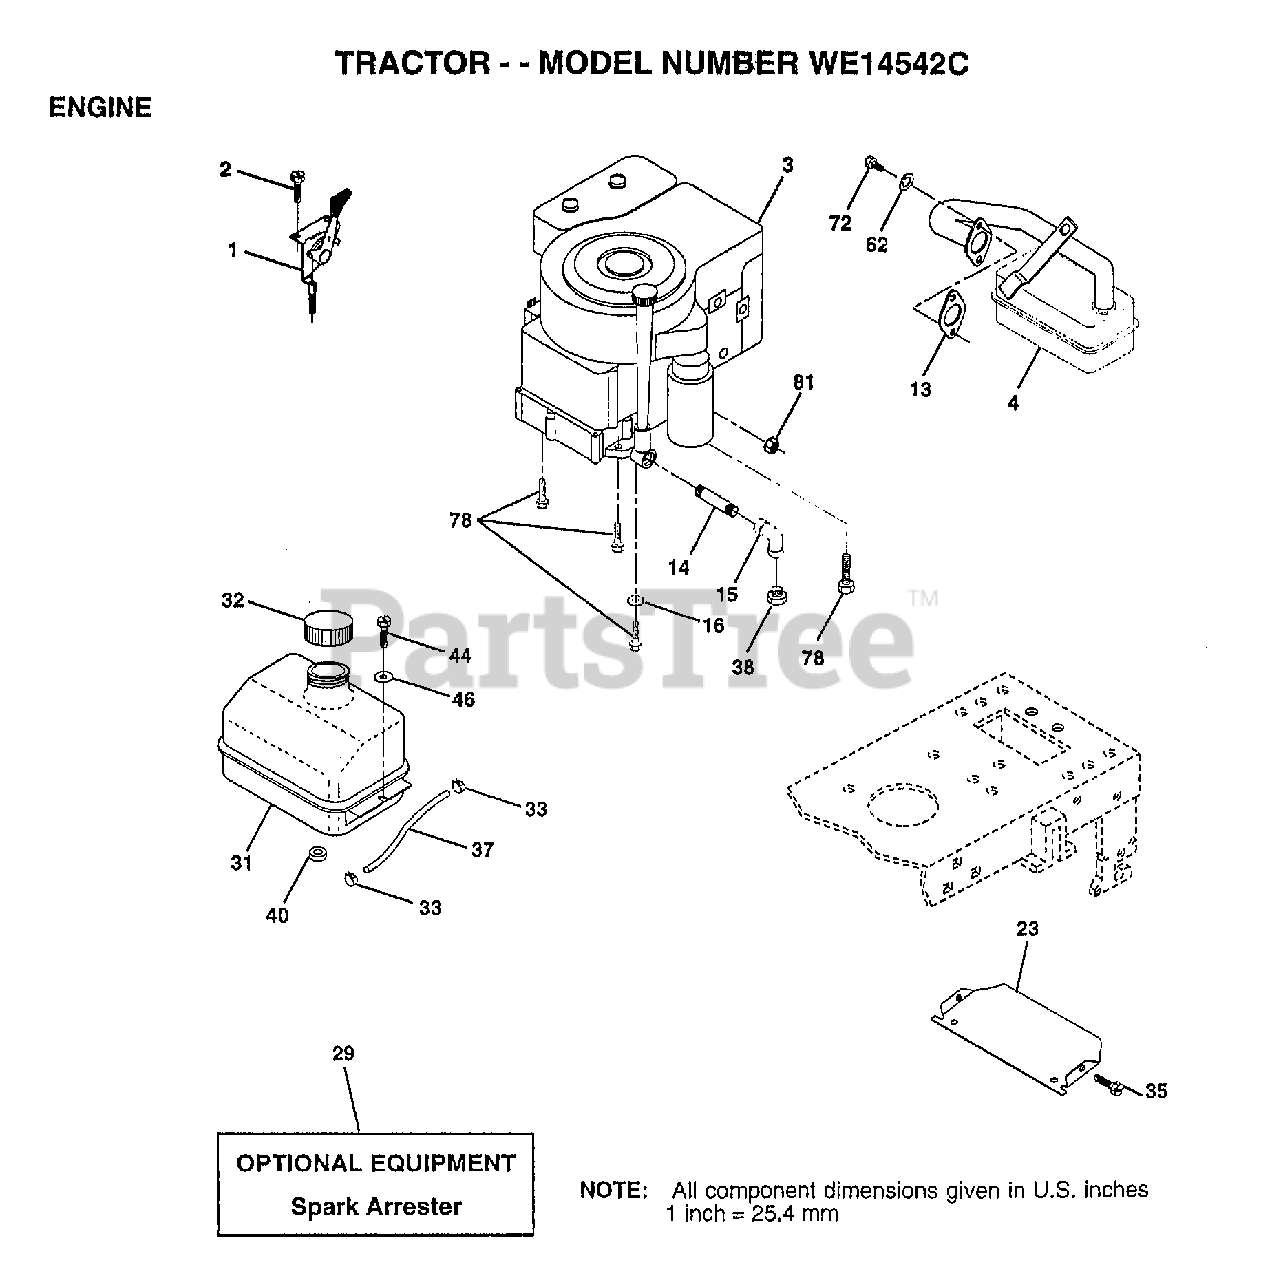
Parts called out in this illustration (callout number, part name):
1	CONTROL THROTTLE
2	SCREW LT
4	MUFFLER
13	GASKET ENG 1 313 LD TIN PLATED
14	PIPE NIPPLE
15	ELBOW
16	LOCKWASHER
23	SHIELD-HEAT
31	TANK.FUEL.LT.
32	CAP ASM FUEL
33	HOSE CLAMP
35	SCREW
37	LINE FUEL
44	SCREW HEX CRT
46	WASHER
62	LOCKWASHER
72	SCREW
78	SCREW
81	NUT
